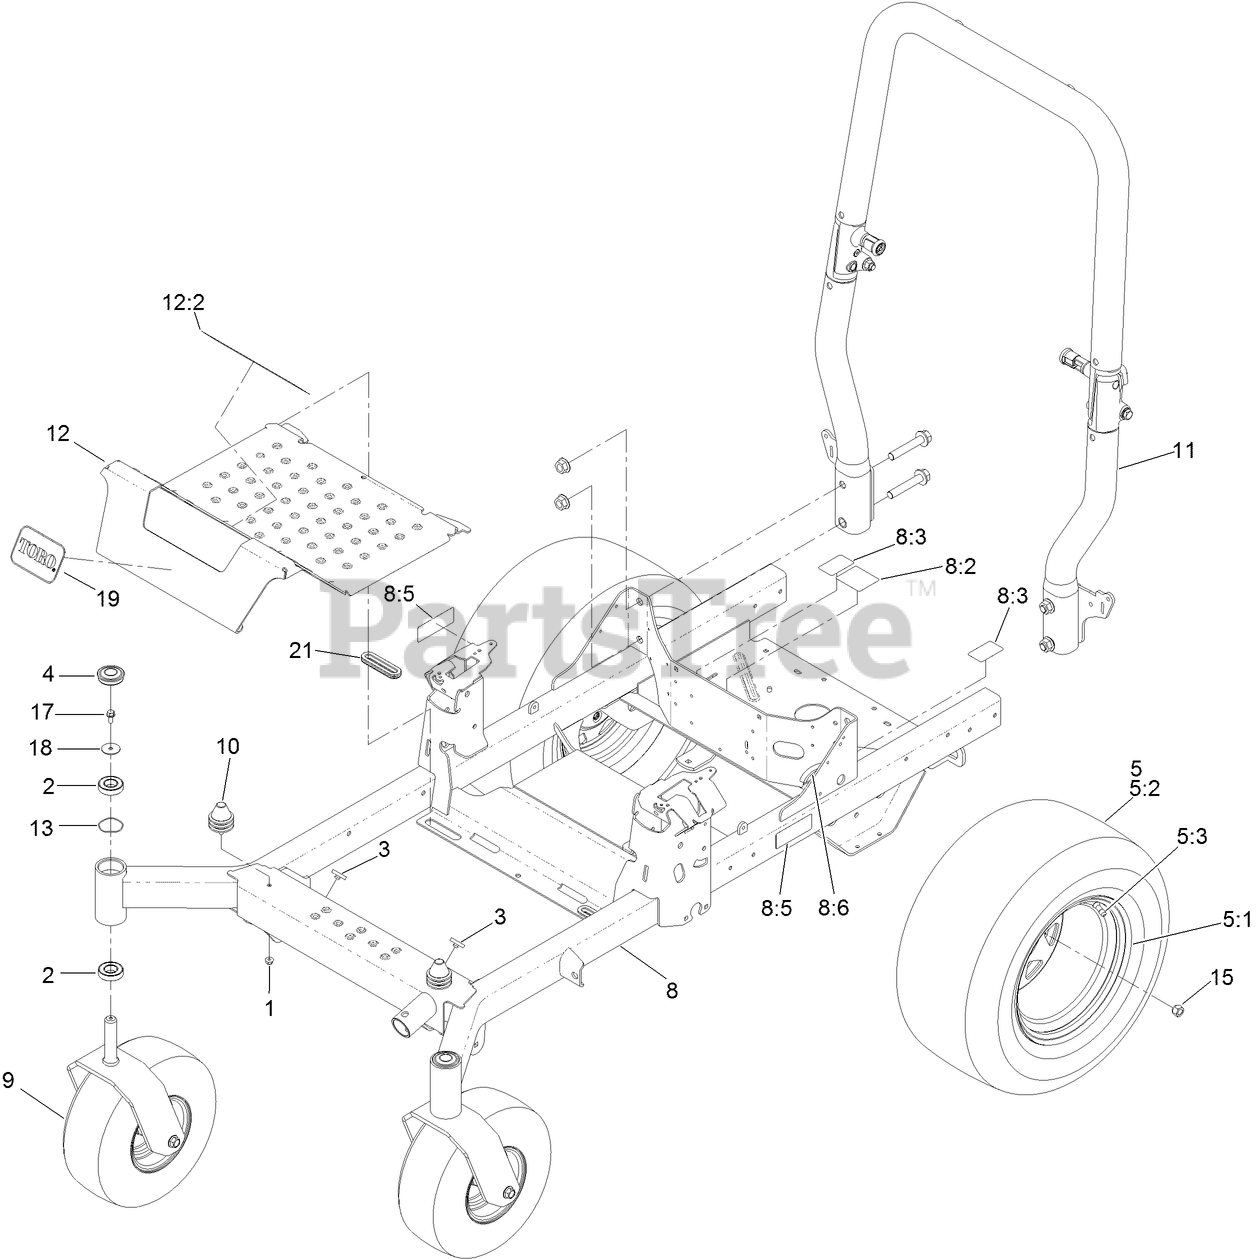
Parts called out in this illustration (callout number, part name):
1	NUT-HF, NI
2	BEARING-BALL
3	BUMPER-PUSH-IN, RUBBER
4	CAP-GREASE
5	WHEEL AND TIRE ASM
5:1	RIM-WHEEL
5:2	TIRE
5:3	STEM-VALVE
8	FRAME ASM
8:2	DECAL-ROUTING, BELT
8:3	DECAL-RELEASE, DRIVE
8:5	DECAL-WARNING
8:6	STRIP-SEAL
9	FRONT CASTER ASM (W/FORK)
10	ISOLATOR
11	ROPS ASM
12	PAN-FLOOR
12:2	DECAL-DANGER
13	SPRING
15	NUT-LUG
17	SCREW-HHF
18	WASHER-FLAT
19	DECAL
21	GROMMET-RUBBER
